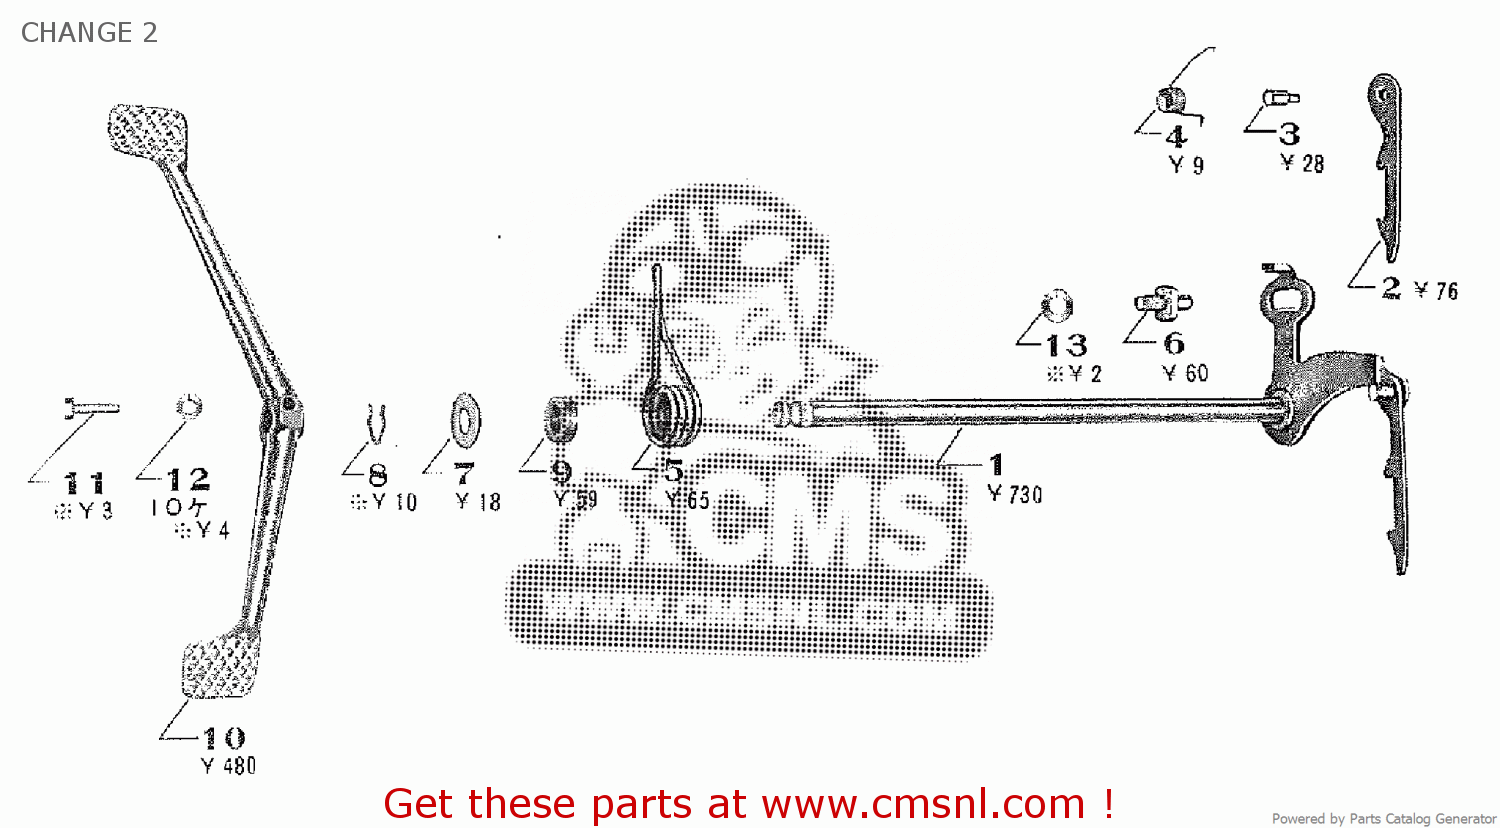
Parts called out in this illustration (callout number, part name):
1	CHANGE SHAFT COMP.
2	CHANGE PAWL
3	CHANGE PAWL PIN
4	CHANGE PAWL RETURN SPRING
5	CHANGE SHAFT RETURN SPRING
6	CHANGE ARM STOPPER
7	CHANGE SHAFT THRUST WASHER
8	CHANGE SHAFT SET CIRCLIP
9	CHANGE SHAFT OIL SEAL
10	CHANGE LEVER
11	6X24 HEXAGON BOLT
12	6MM SPRING WASHER
13	8MM SPRING WASHER
